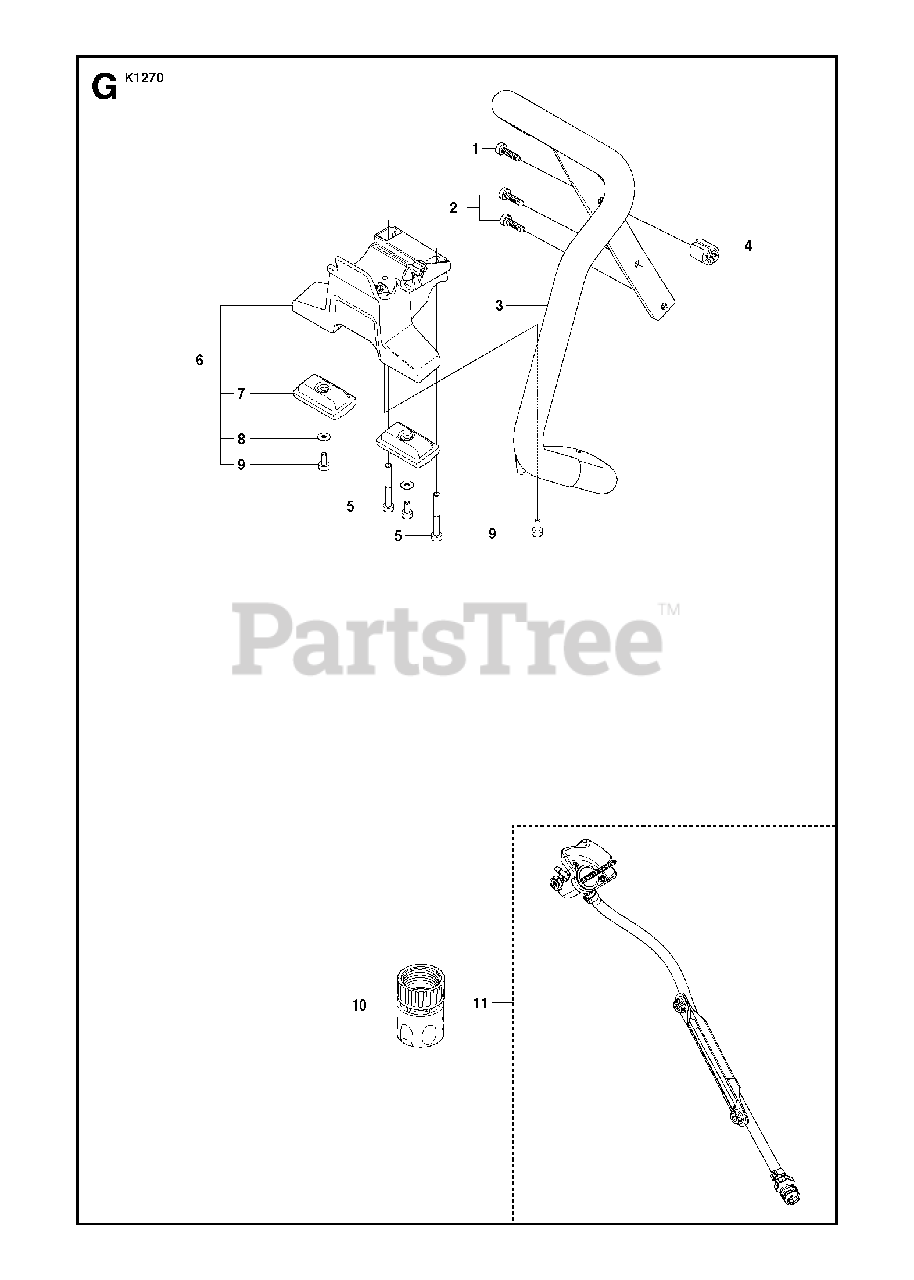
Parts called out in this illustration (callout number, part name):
1	SCREW ITXSCM
2	SCREW ITXSCT
3	HANDLE
4	ANTIVIBRATION ELEMENT
5	SCREW ITXSCM
6	GROUND SUPPORTIncl. 7 - 9
9	SCREW ITXSCT
10	COUPLERUSA, Canada
